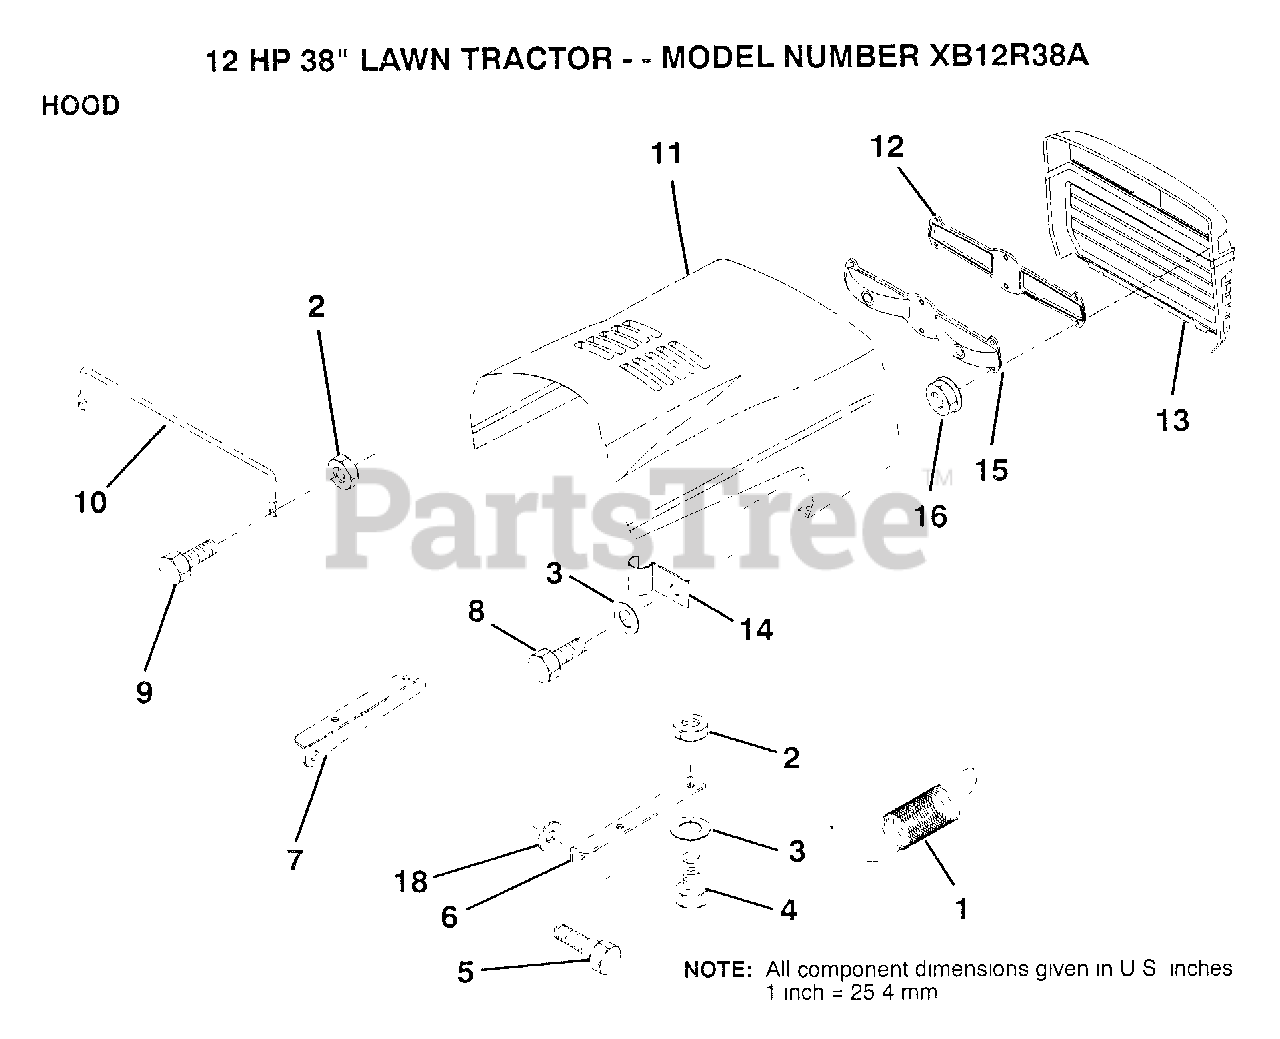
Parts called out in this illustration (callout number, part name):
1	EXT SPRING
2	NUT
3	WASHER
4	BOLT
6	BRKT HOOD RH
7	BRKT HOOD LH
10	"BRACE,HOOD"
13	GRILL (BLACK)
14	CLIP T
16	NUT
18	WASHER
